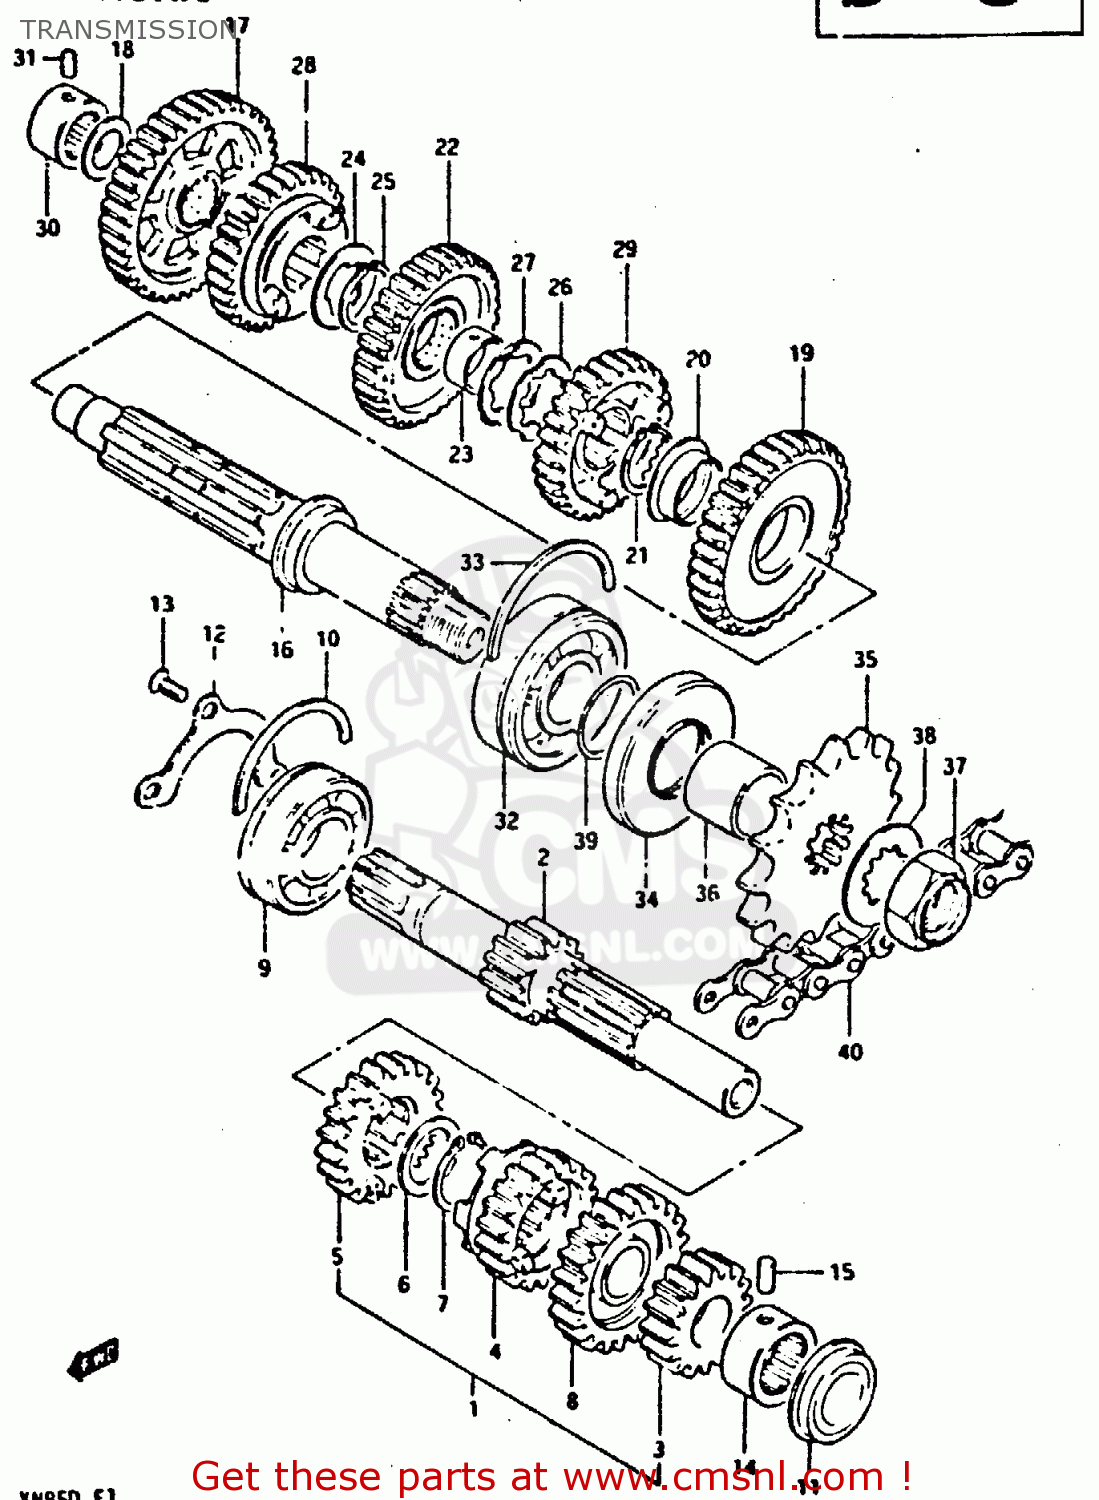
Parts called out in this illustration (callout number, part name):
1	SHAFT,COUNTER
2	SHAFT,COUNTER
3	GEAR,SECOND DRIVE
4	GEAR,THIRD DRIVE
5	GEAR,FOURTH DRIVE
6	WASHER,LOCK
7	CIRCLIP
8	GEAR,FIFTH DRIVE
9	BEARING(25X62X17)
10	C-RING
11	PLUG
12	RETAINER,CNTR SHAFT BEARING
13	SCREW
14	BEARING
15	PIN
16	SHAFT,DRIVE
17	GEAR,FIRST DRIVEN
18	WASHER,THRUST
19	GEAR,SECOND DRIVEN
20	BUSH(28X32X2)
21	CIRCLIP
22	GEAR,THIRD DRIVEN
23	BUSH,3RD DRIVEN GEAR
24	WASHER,LOCK
25	CIRCLIP
26	WASHER,LOCK
27	WASHER
28	GEAR,FOURTH DRIVEN
29	GEAR,FIFTH DRIVEN
30	BEARING(20X34X20)
31	PIN
32	BALL BEARING 25X62X17
33	C-RING
34	SEAL,OIL(32X62X7)
35	SPROCKET,ENGINE(NT:16)
36	SPACER
37	NUT
38	WASHER
39	O RING(D:1,ID:24.5)
40	CHAIN ASSEMBLY,DRIVE
